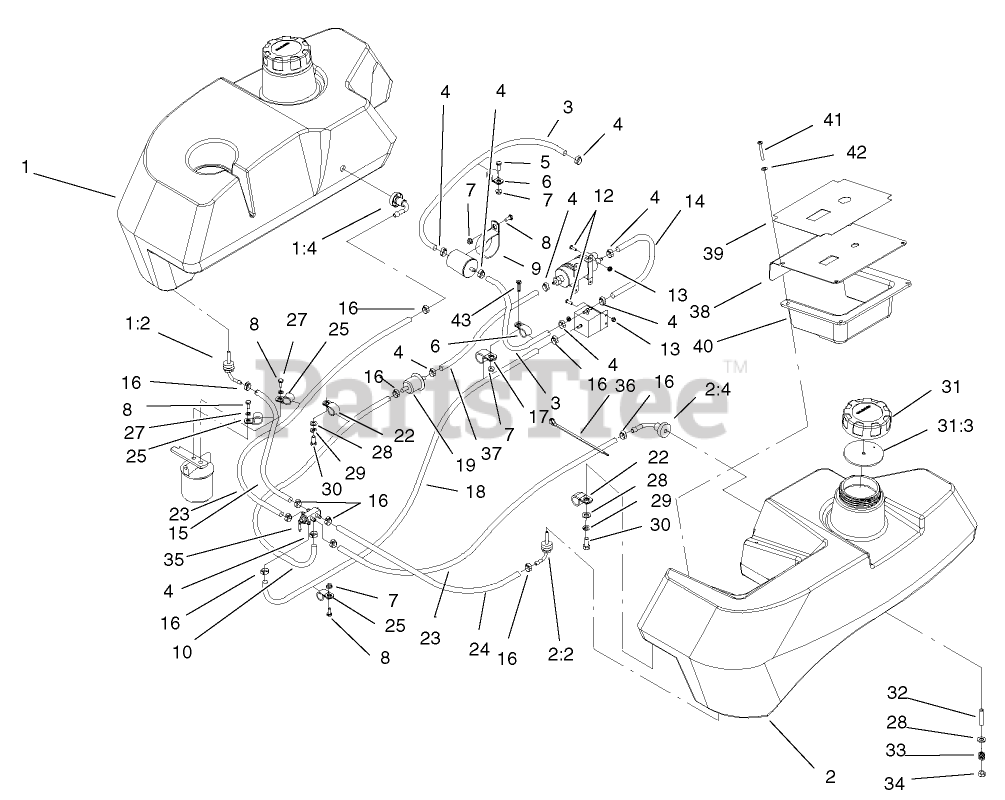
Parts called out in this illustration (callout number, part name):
1	ASM, TANK-FUEL RH
1:2	FITTING-FUEL, BULKHEAD
1:4	Fitting-Fuel, Bulkhead
2	ASM, TANK-FUEL LH
2:2	FITTING-FUEL, BULKHEAD
2:4	Fitting-Fuel, Bulkhead
3	Hose-Fuel
4	CLAMP-HOSE, FUEL
5	SCREW-HH
6	CLIP-LOOM
7	NUT-HF
8	SCREW-HH
9	CLIP-LOOM
10	HOSE-FUEL
12	SCREW-PPH
13	NUT-LOCK, NI
14	Hose-Fuel
15	Hose-Fuel
16	CLAMP-HOSE, FUEL
17	CLIP-LOOM
18	Hose-Fuel
19	Connector
23	HOSE-FUEL
24	HOSE-FUEL
25	CLIP-LOOM
27	WASHER-LOCK
28	WASHER-PLAIN
29	WASHER-LOCK
30	SCREW-HH
31	GAS CAP ASM
31:3	GASKET-CAP, GAS
33	SPRING-TANK, FUEL
34	NUT-LOCK, NI
35	VALVE-FUEL, DUAL FLOW
36	TIE-CABLE
37	HOSE-FUEL
38	Panel-Control
39	DECAL-PANEL, CONTROL
40	SHIELD-PANEL, CONTROL
42	WASHER-SPRING
43	SCREW-HH
